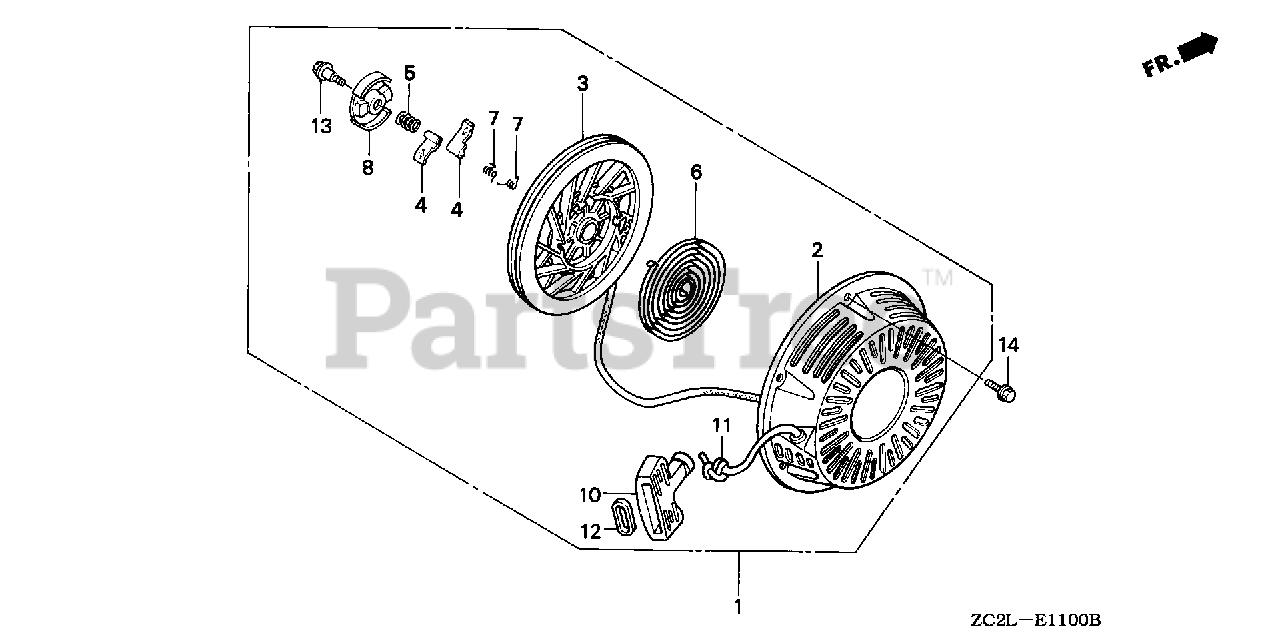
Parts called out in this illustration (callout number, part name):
1	STARTER ASSY., RECOIL *NH16M* (GUN METALLIC BLACK) (NOT AVAILABLE)
1	STARTER ASSY., RECOIL *NH1* (BLACK)
2	CASE, RECOIL STARTER *NH1* (BLACK)
2	CASE, RECOIL STARTER *NH16M* (GUN METALLIC BLACK)
3	PULLEY, RECOIL STARTER
4	RATCHET, STARTER
5	SPRING, FRICTION
6	SPRING, STARTER RETURN
7	SPRING, RATCHET
8	RETAINER, SPRING
10	GRIP, STARTER
11	ROPE, RECOIL STARTER
12	REINFORCEMENT, GRIP
13	SCREW, CENTER
14	BOLT, FLANGE (6X8)
